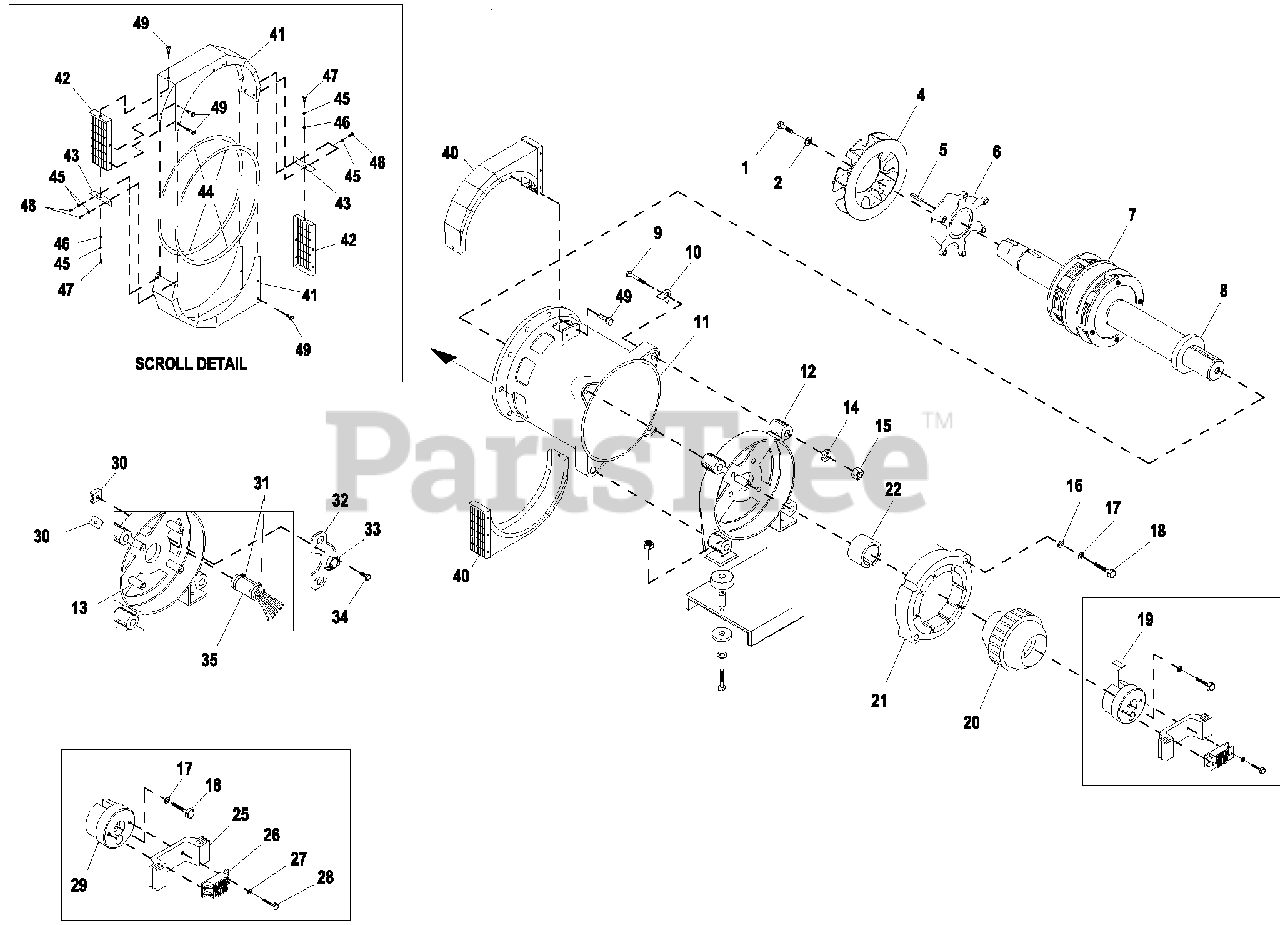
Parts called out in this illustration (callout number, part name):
1	SCREW HHC M8-1.25X 20 G10.9
2	WASHER LOCK M8-5/16
4	FAN SAE ALTERNATOR (G/B)
5	KEY SQ 3/8X1-9/16 STEEL
6	HUB DRIVE 390 SAE GB
7	RTR 390 100KB3 GB SAE TECHUM
8	BEARING BALL 6212 SEALED
9	SCREW HHC M14-2.0X 140 G8.8
10	WASHER 390 SAE ALT.
11	STR-390-80LB3 SAE
12	CARRIER REAR BRG 15"
13	PIN DOWEL 1/2 X 1-1/4
14	WASHER LOCK M14
15	NUT HEX M14-2.0 G8 YELCHR
16	WASHER FLAT M12
17	WASHER LOCK M12
18	SCREW HHC M12-1.75 X 6 0 G10.9
19	KEY SQ 3/8 X 3-1/4 STEEL
20	ASSY EXCITER 2.00" STK
21	EXITER FIELD 2" LGSPD CONN
22	COLLAR SLIP FIT 390 MM
25	BRIDGE SUPPORT DIODE 15"
26	ASSY BRIDGE RECTIFIER
27	WASHER SHAKEPROOF INT #8
28	SCREW HHM #8-32 X 7/8
29	CAP END ROTOR 390MM
30	PLATE NUT
31	TIE WRAP UL 14.6 X.14 NATL
32	BRACKET-STATORWIRE
33	CLAMP HOSE #36 1.88-2.7
34	SCREW HHC 5/16-18 X 1-1/4 G5
35	SLEEVE RUBBER
40	ASSY SCROLL 390 SAE
41	SHROUD ALT SHEET METAL
42	SCREEN SHROUDSAE
43	BRKT TENSIONER SAE SCROLL
44	TRIM VINYL BLACK 1/8 GP
45	WASHER LOCK M6-1/4
46	WASHER FLAT 1/4-M6 ZINC
47	SCREW HHC M6-1.0X25 G8.8
48	SCREW HHC M6-1.0 X 16 G8.8
49	SCREW SWAGE 1/4-20 X 1/2 ZYC
